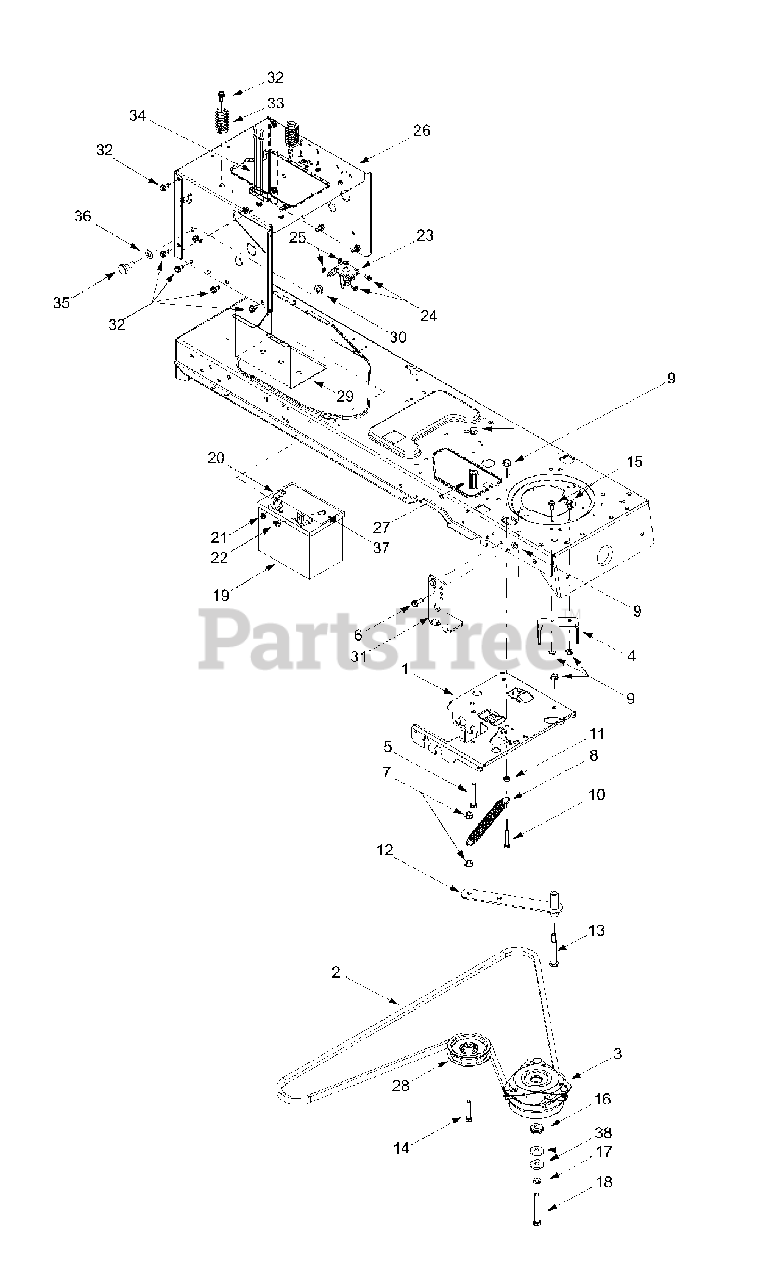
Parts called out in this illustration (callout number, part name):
2	PTO Belt (Models w/ 46-inch deck)
3	Electric PTO Clutch
6	Hex Head Washer Screw, 5/16-18 x .875
7	Flange Lock Nut, 3/8-16
8	Extension Spring, .62 x 5.62
9	Flange Lock Nut, 5/16-18
10	Hex Cap Screw, 5/16-18 x 1.75
11	Hex Nut, 5/16-18
14	Hex Cap Screw, 3/8-16 x 2.0
15	Hex Cap Screw, 5/16-18 x .625
16	Shoulder Spacer, 1.38 x .445 x .36
17	Lock Washer, 7/16
18	Hex Cap Screw, 7/16-20 x 3.25 (Grade 5)
19	12-volt Battery, 270 CCA
20	Hex Cap Screw, 1/4-20 x .62
21	Hex Sems Nut, 1/4-20
22	Wing Nut, 1/4-20
23	Solenoid, 12-Volt, 100 Amp
24	Self Tapping Screw, 1/4-20 x .5
25	Lock Washer, 1/4
28	Idler Pulley, 3.5
32	Self Tapping Screw, 5/16-18 x .625
33	Compression Spring, 1.28 x 3.5
34	Battery Strap
35	Shoulder Screw, .625 x .5, 7/16-20
36	Bell Washer, .45 x 1.0 x .062
37	Shoulder Screw, 1/4-20, .25 x .15
38	Flat Washer, .45 x 1.25 x .164
